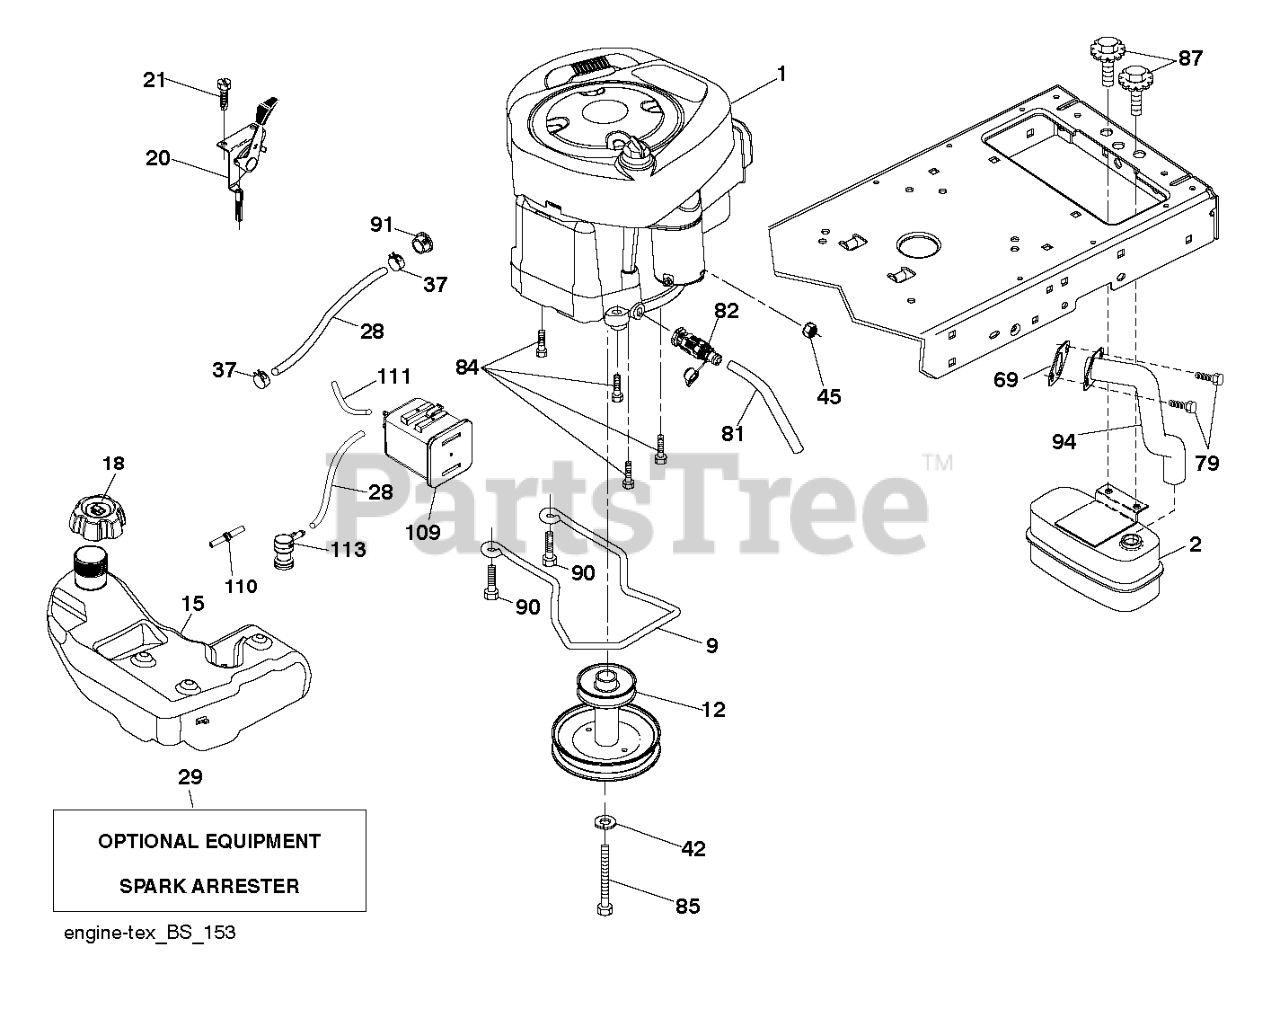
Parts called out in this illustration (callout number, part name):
2	MUFFLER.ASM.SINGLE
12	PULLEY.ENGINE
15	FUEL TANKS
18	FUEL CAP
18	Fuel Caps
20	CONTROL.TH/CK.C.
28	LINE.FUEL.64"REAR.EMIS
29	KIT.SPARK ARRESTOR 794945 B&S
37	HOSE CLAMP
69	REPL BY 532 27 22-93
81	TUBE, DRAIN OIL ASM.
82	VALUE.OIL.DRAIN
84	SCREW.3/8-16
85	BOLT.HEX.7/16-20X4.GR5.1.5BLUE
87	BOLT.5/16-18UNCX3/4 W/SEMS.BLK
90	SCREW 3/8-16X1
91	BUSHING.1.375OD
94	EXHAUST.TUBE.B&S.28/31
109	CANNISTER, CARBON
110	VALVE.ASM.ANTI-SLOSH
111	TUBE.PURGE.FUEL.1875
113	VALVE.SLANT.CARTRDG.90 DEG.TEX
